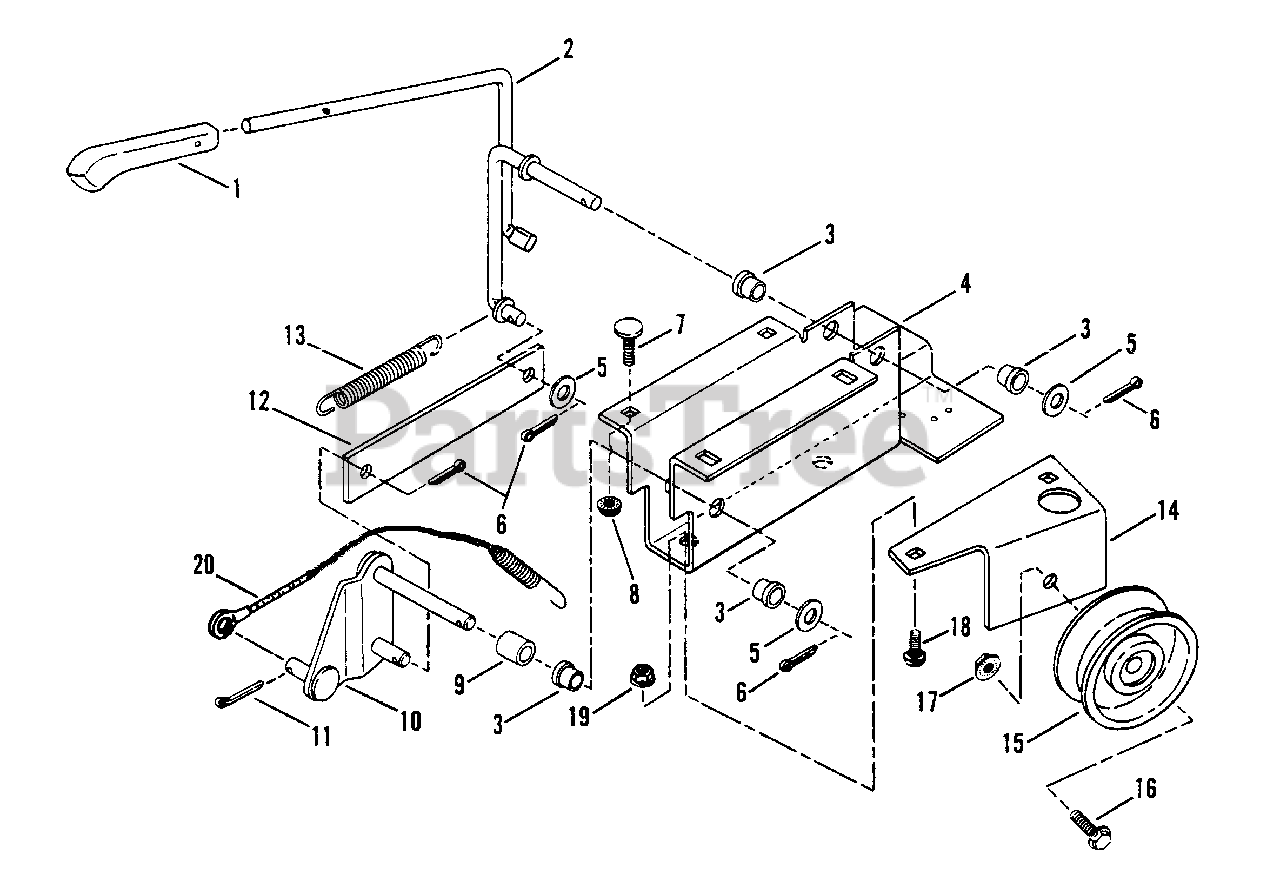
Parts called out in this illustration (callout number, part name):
1	KNOB, Handle 7/16"
2	HANDLE, Blade Engagement (No longer available, try using 7040674)
3	BUSHING
4	BRACKET, Handle
5	WASHER, 3/8 SAE YZ
6	PIN, 3/32 x 3/4" Cotter
7	BOLT, 1/4-20 x 5/8" Flat Head Carriage
8	NUT, 1/4-20 Hex Flange Lock
9	SPACER .625 OD x .380 ID x .560 L
10	ASSEMBLY, Pivot Arm
11	PIN, 3/32 x 1" Cotter
13	SPRING, Return
14	BRACKET, Idler Support
15	PULLEY, Idler 2.75" OD
16	BOLT, 3/8-16 x 1-3/4" Hex Flange Lock
17	NUT, 3/8-16 Hex Lock
18	BOLT, 5/16-18 x 1/2" Short Neck Carriage
19	NUT, 5/16-18 Hex Lock Flanged
20	CABLE, Blade (35.0" Long - 38" Models)
20	CABLE, Blade (30.44" Long - 42" Models)
20	CABLE, Blade (21.5" Long - 48" Models)
